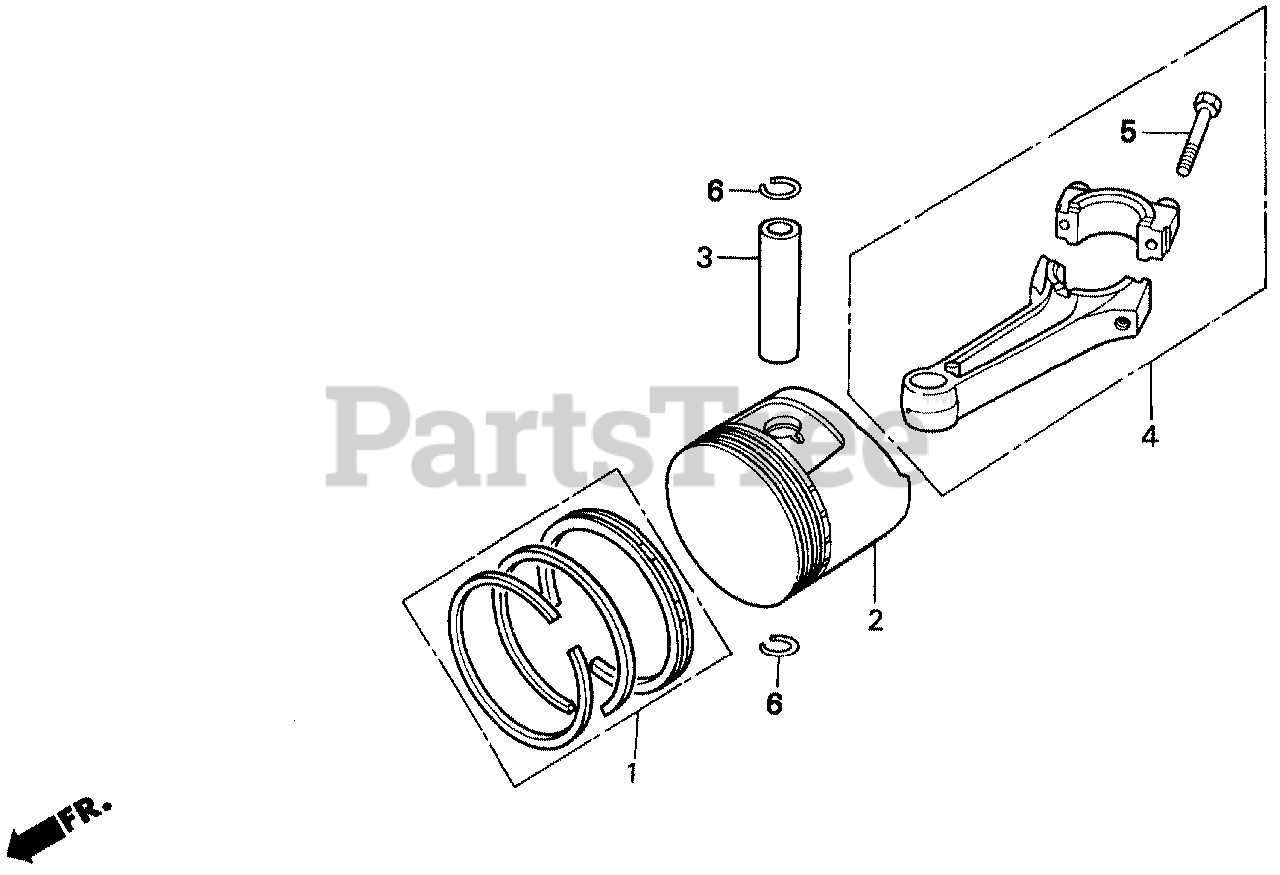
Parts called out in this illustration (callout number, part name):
1	RING SET, PISTON (STD)
1	RING SET, PISTON (OS 0.25)
1	RING SET, PISTON (OS 0.50)
1	RING SET, PISTON (0.75)
2	PISTON (STD)
2	PISTON (OS 0.25)
2	PISTON (OS 0.50)
2	PISTON (0.75)
3	PIN, PISTON
4	ROD ASSY., CONNECTING
4	ROD ASSY., CONNECTING (US)
5	BOLT, CONNECTING ROD
6	CLIP, PISTON PIN (18MM)
